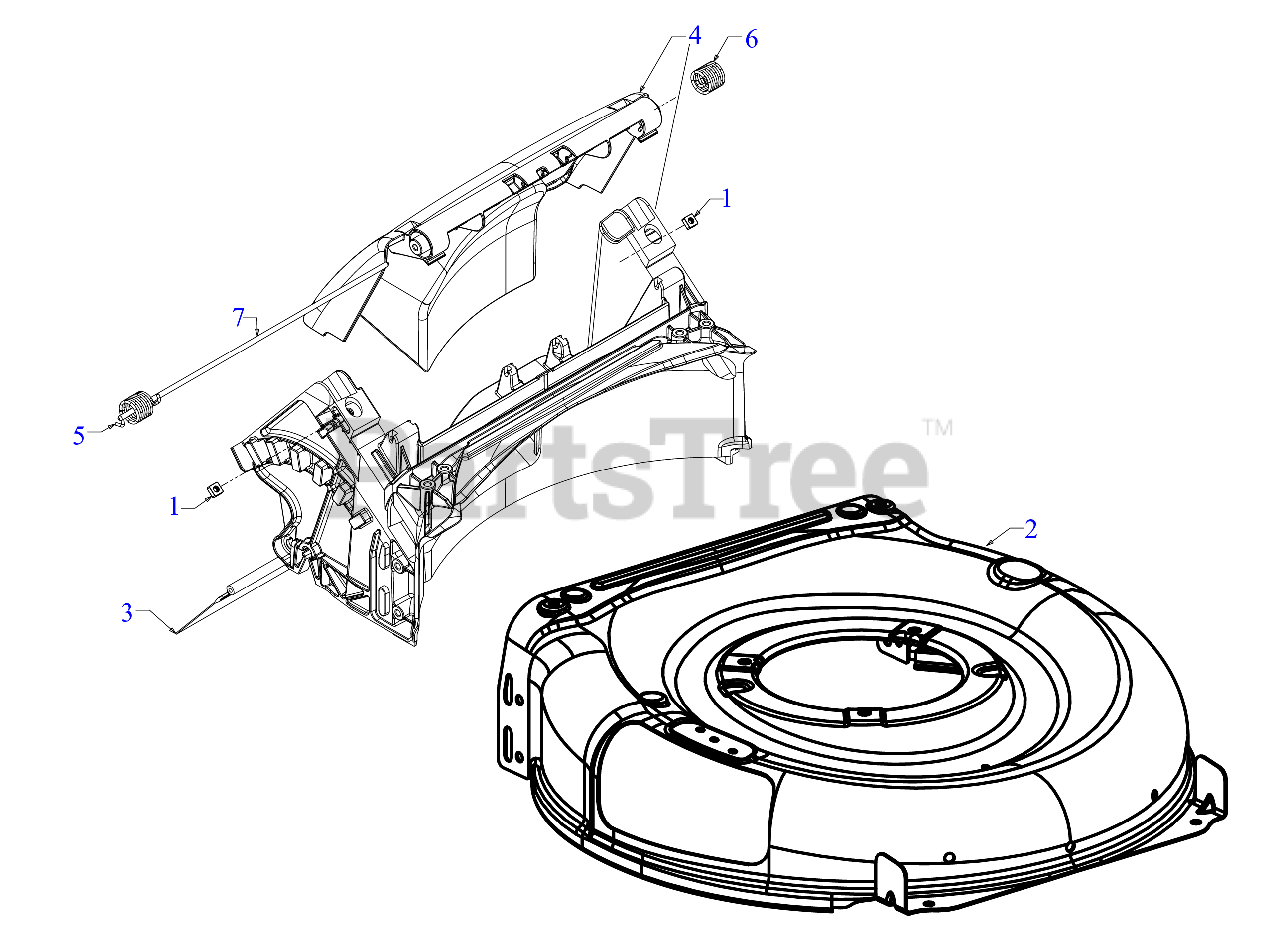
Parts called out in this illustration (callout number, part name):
1	SQUARE NUT 1/4-20
3	TRAILSHIELD
4	REAR BAFFLE
5	TORSION SPRING (RH)
6	TORSION SPRING (LH)
7	REAR DOOR PIVOT ROD
